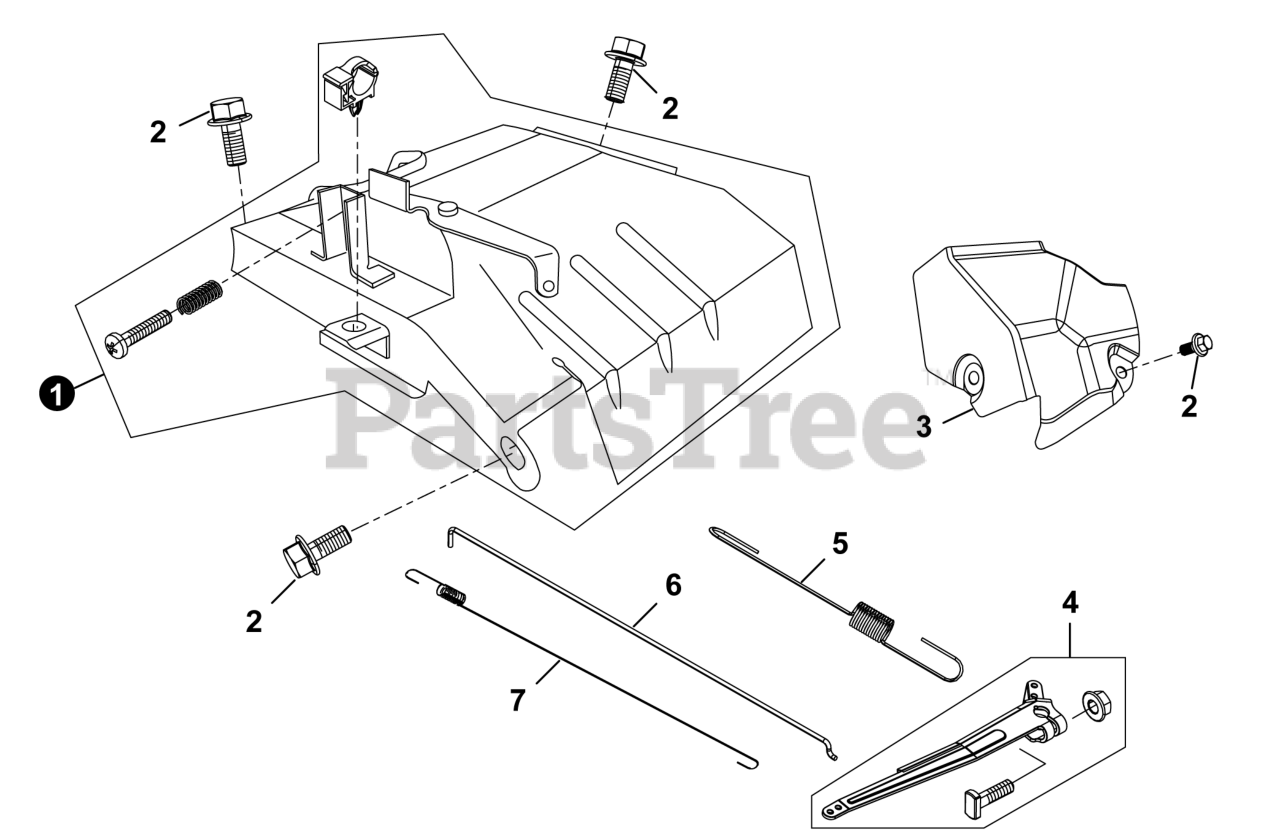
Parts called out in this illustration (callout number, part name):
1	THROTTLE CONTROL ASSEMBLY
3	COVER,GOVERNOR
4	SUPPORT SUBASSEMBLY, GOVERNOR
5	SPRING, GOVERNOR
6	ROD, GOVERNEOR
7	SPRING, THROTTLE VALVE RETURNING
